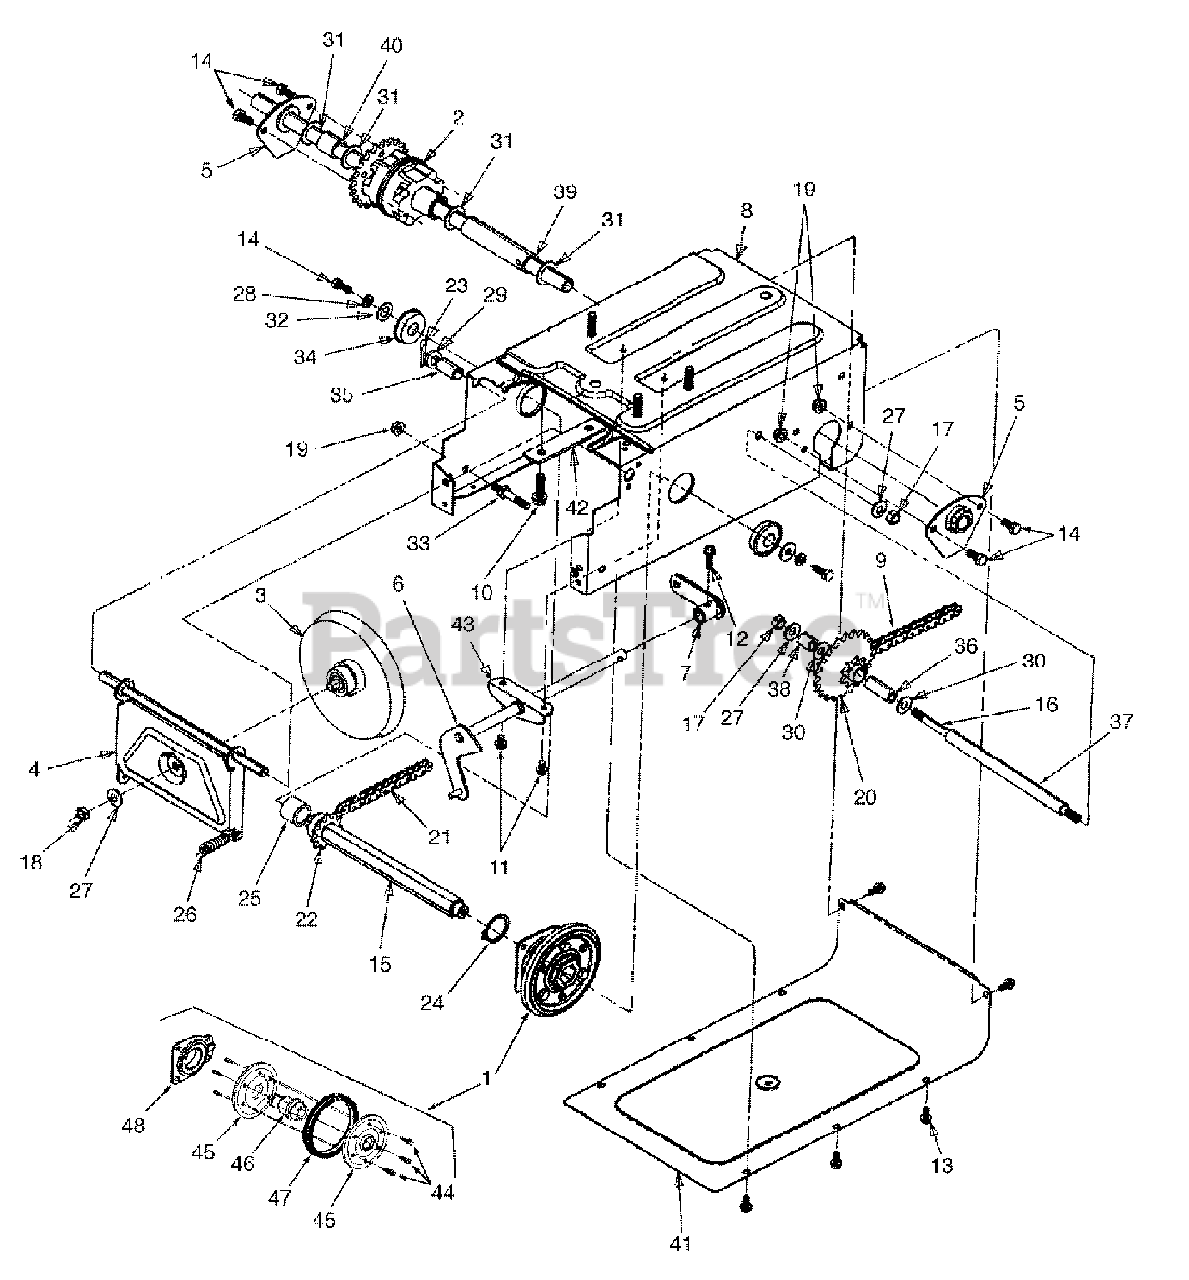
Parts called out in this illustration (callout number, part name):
1	Friction Wheel Ass'y Complete
2	Differential Ass'y Complete
3	Friction Disc Assembly
4	Bracket Ass'y, Frctn Wheel Supt
5	Bracket Ass'y, Axle
6	Shaft Ass'y, Shift
9	Chain, #420 x 36 Lnks
10	Screw, Hex Wash Hd Tapp 3/8-16 x 1.25
11	Screw, Hex Wash Hd Tapp 1/4-20 x .375
12	Screw, Hex Wash Hd Tapp 1/4-20 x 1.0
13	Screw, Hex Wash Hd Tapp 1/4-14 x .625
14	Screw, Hex Cap, 5/16-18 x .75 GR5
15	Hex Shaft
16	Jack Shaft
17	Nut, Hex, 3/8-24
18	Nut, Hex Jam, 3/8-24
19	Nut, Hex Flange Lock, 5/16-18 GR5
20	Sprocket Ass'y, 9T & 22T
21	Chain, #41 x 36 Lnks
22	Sprocket, 10T
23	Pin, Cotter, 3/32 x 1.0
24	Ring, Snap, 1.0 Dia
25	Spacer, .675 x 1.0 x 1.53
26	Spring, Extension
27	Washer, Bell, .406 x .870 x .063
28	Washer, Lock, 5/16
29	Washer, Flat, .536 x .930 x .05
30	Washer, Flat, .385 x .87 x .06
31	Washer, Flat, .793 x 1.24 x .06
32	Washer, Flat, .345 x 1.0 x .100
33	Bolt, Idler
34	Bearing, Ball
35	Spacer, .508 x .75 x .94
36	Sleeve, .380 x .623 x 1.5
37	Spacer, .407 x .625 x 7.86
38	Spacer, .407 x .625 x .71
39	Spacer, .782 x 1.0 x 4.11
40	Spacer, .782 x 1.0 x .99
41	Cover, Frame Bottom
44	Screw, Hex Wash Hd Tapp 1/4-20 X .5
45	Plate, Friction Wheel
46	Hub, Friction Wheel
47	Wheel, Rubber Friction
48	Bearing Ass'y, Friction Wheel
